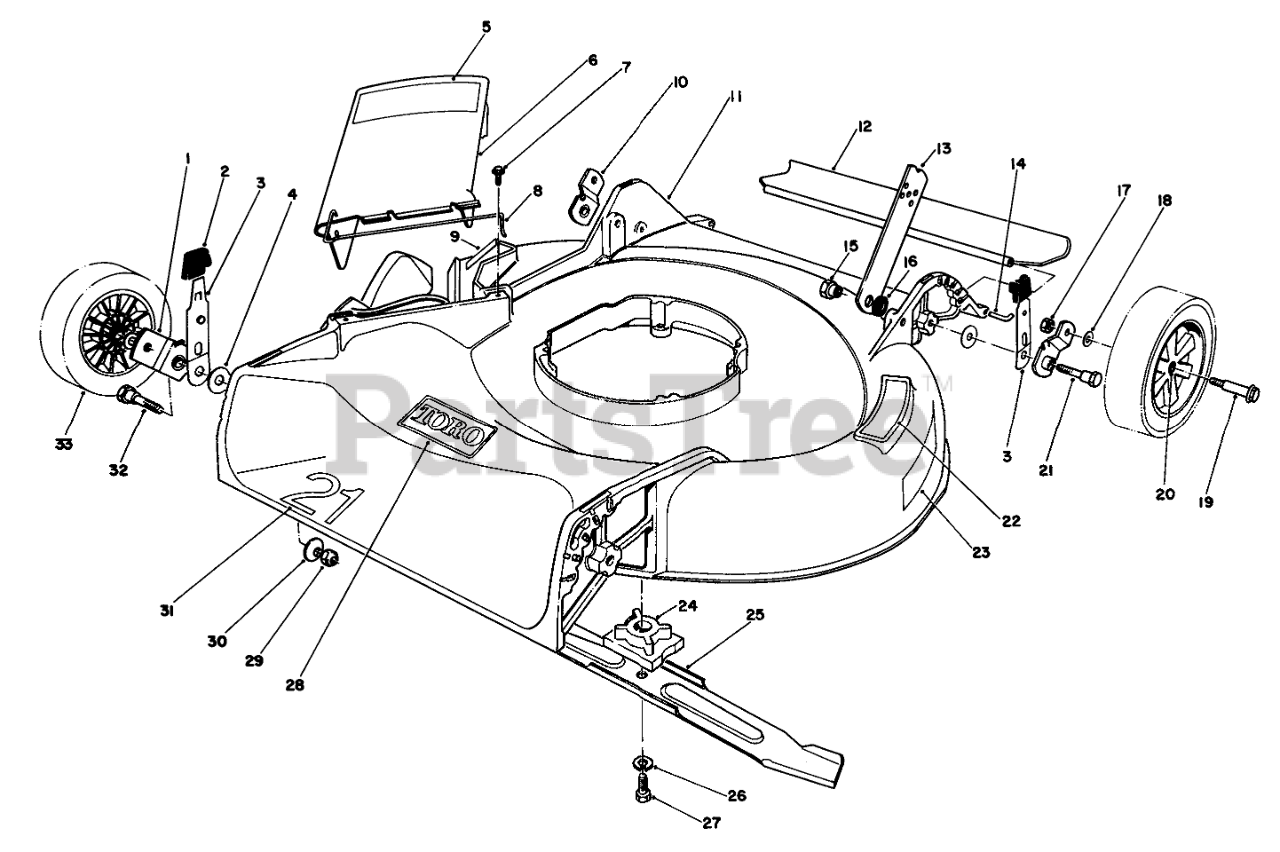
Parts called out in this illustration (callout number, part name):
1	Pivot Arm
2	KNOB-ARM
3	SPRING ARM ASM
4	WASHER-PIVOT
5	Decal-Danger
6	Deflector Assembly (Incl.Ref. #5 & 8)
7	SCREW-HWH
8	SPRING HINGE
9	Decal-Danger
10	Pivot Arm
11	HOUSING/DECAL
12	REAR SAFETY SHIELD 21
13	HANDLE LATCH
14	SHIELD ROD
15	HANDLE PIVOT NUT
16	SPACER
17	NUT-LOCK
18	WASHER
19	WHEEL BOLT
20	BUSHING
21	PIVOT SCREW
22	STEP PAD DECAL
23	Decal-Step Pad
24	BLADE RETAINER
25	Blade
26	WASHER-LOCK
27	SCREW-HH
28	Decal Tow
29	NUT-LOCK, NI
30	WASHER-BELLEVILLE
31	Decal-21"
32	PIVOT SCREW
33	Wheel & Tire Assembly (Incl Ref. #20)
